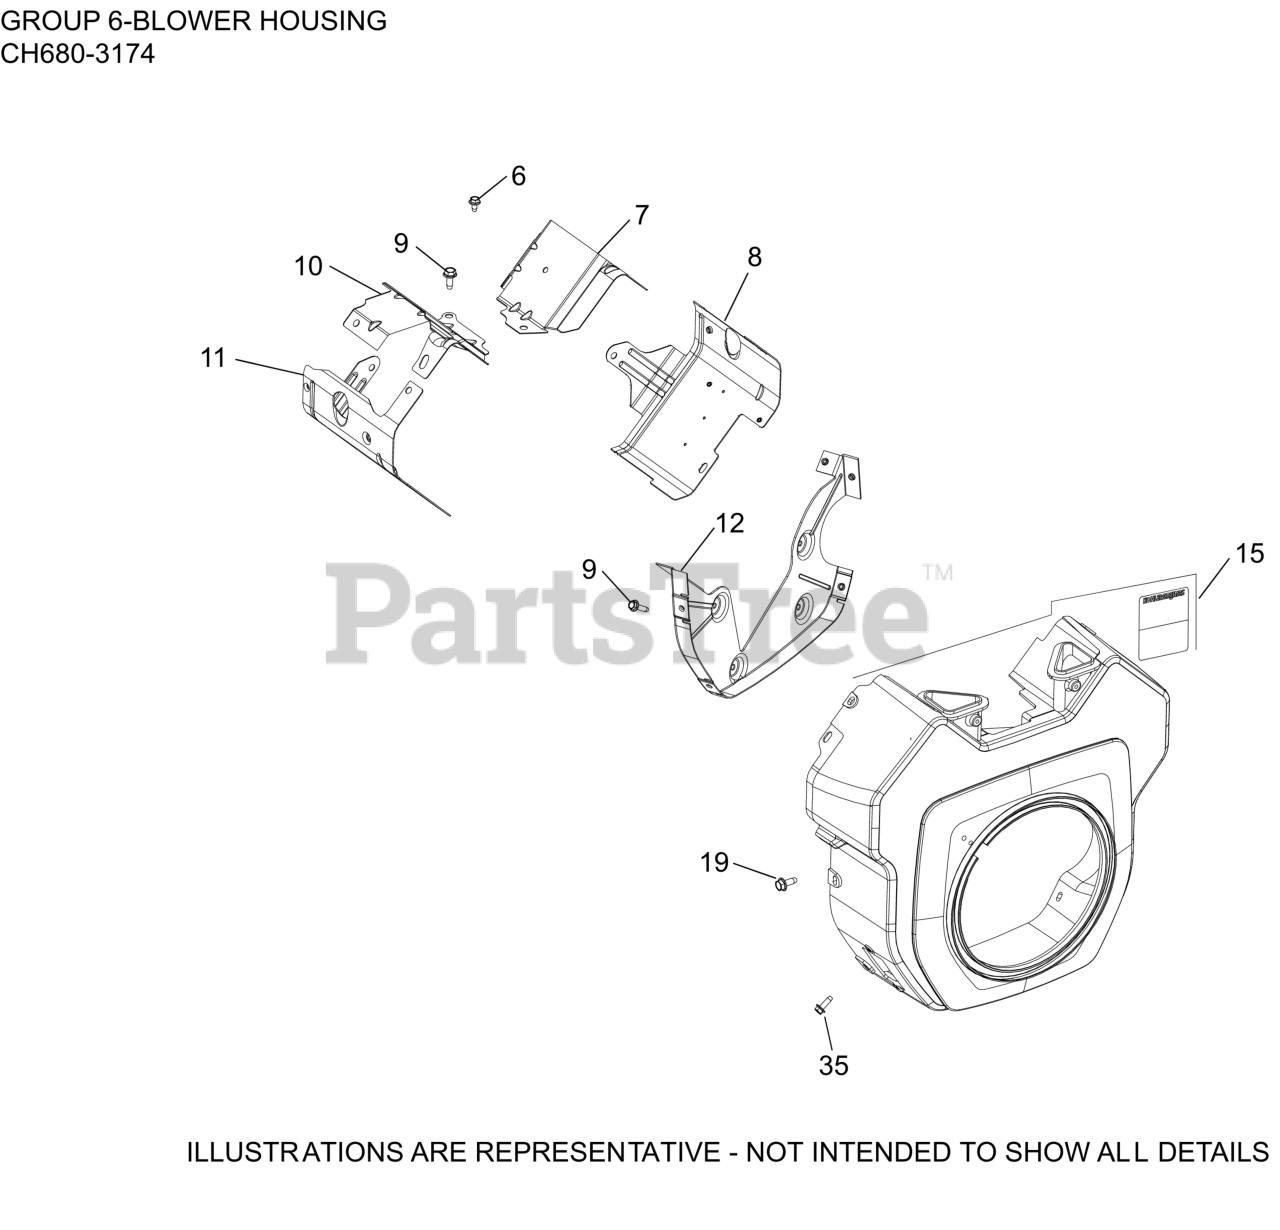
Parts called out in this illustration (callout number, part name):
6	SCREW, THREAD FORMING
7	BAFFLE, VALLEY #1 CYLINDER
8	KIT, CYL BAFFEL #1 SIDE
9	SCREW, THREAD FORMING
10	BAFFLE, VALLEY #2 CYLINDER
11	BAFFLE, LEFT BARREL
12	KIT, BACKING PLATE
15	HOUSING, BLOWER
15	KIT, BLOWER HOUSING
19	SCREW, THREAD FORMING
35	SCREW, THREAD FORMING
